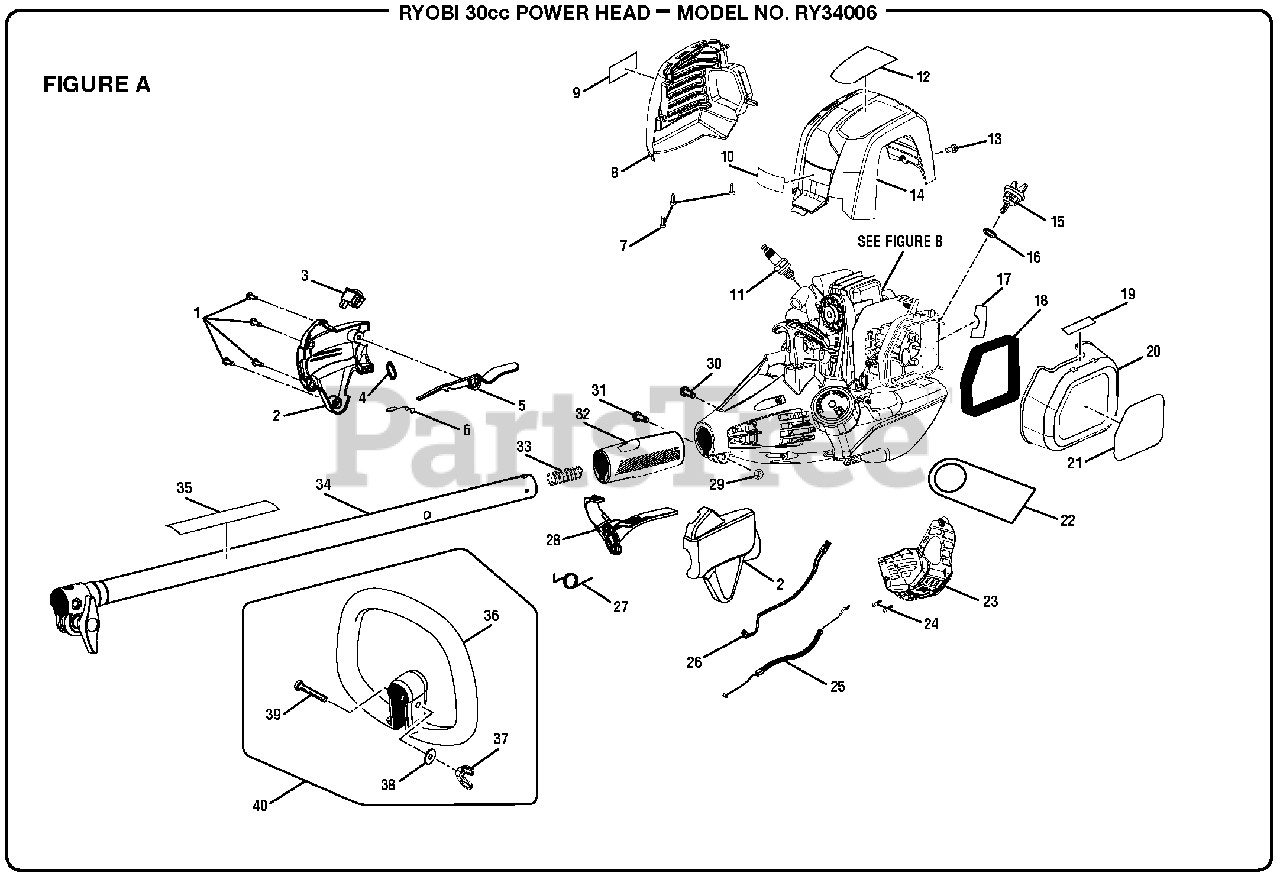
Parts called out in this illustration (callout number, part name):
1	Screw (M4 x 20 mm, T20 Torx Pan Hd.)
2	Control Handle Assembly
3	Switch (Momentary Contact)
4	Strap Hanger
5	Trigger Lock
7	Screw (M4 x 12 mm, T20 Truss Hd.)
8	Muffler Housing
9	Combustion Warning Label
10	Logo Label
11	Spark Plug (Champion RY4C)
12	X430 Label (RY34006)
13	Shoulder Screw (M4 x 11 mm, T20 Torx Pan Hd.)
14	Top Cover
15	Oil Cap/Dipstick
17	Hot Surface Label
18	Air Filter
19	Choke Label
20	Air Filter Cover
21	Starting Label
22	Oil Hang Tag
23	Bottom Cover
24	Screw (#6-19 x 1/2 in., Phillips Hd. T.F.)
25	Throttle Cable
26	Lead Assembly
27	Torsion Spring (Throttle Trigger)
28	Throttle Trigger
29	Hex Nut (M6.3 x 1)
30	Screw (#8-16 x 5/16 in., T25 Torx Pan Hd. T.F.)
31	Bolt (M6 x 20 mm, T27 Torx Button Hd.)
32	Rear Handle
33	Compression Spring
34	Upper Boom Assembly
35	Warning Label
36	Front Handle
37	Wing Nut (1/4-20)
38	Washer (ID7 x OD19 x 1-3/4t)
39	Screw (1/4-20 x 40 mm, Hex Hd.)
40	Front Handle Assembly
